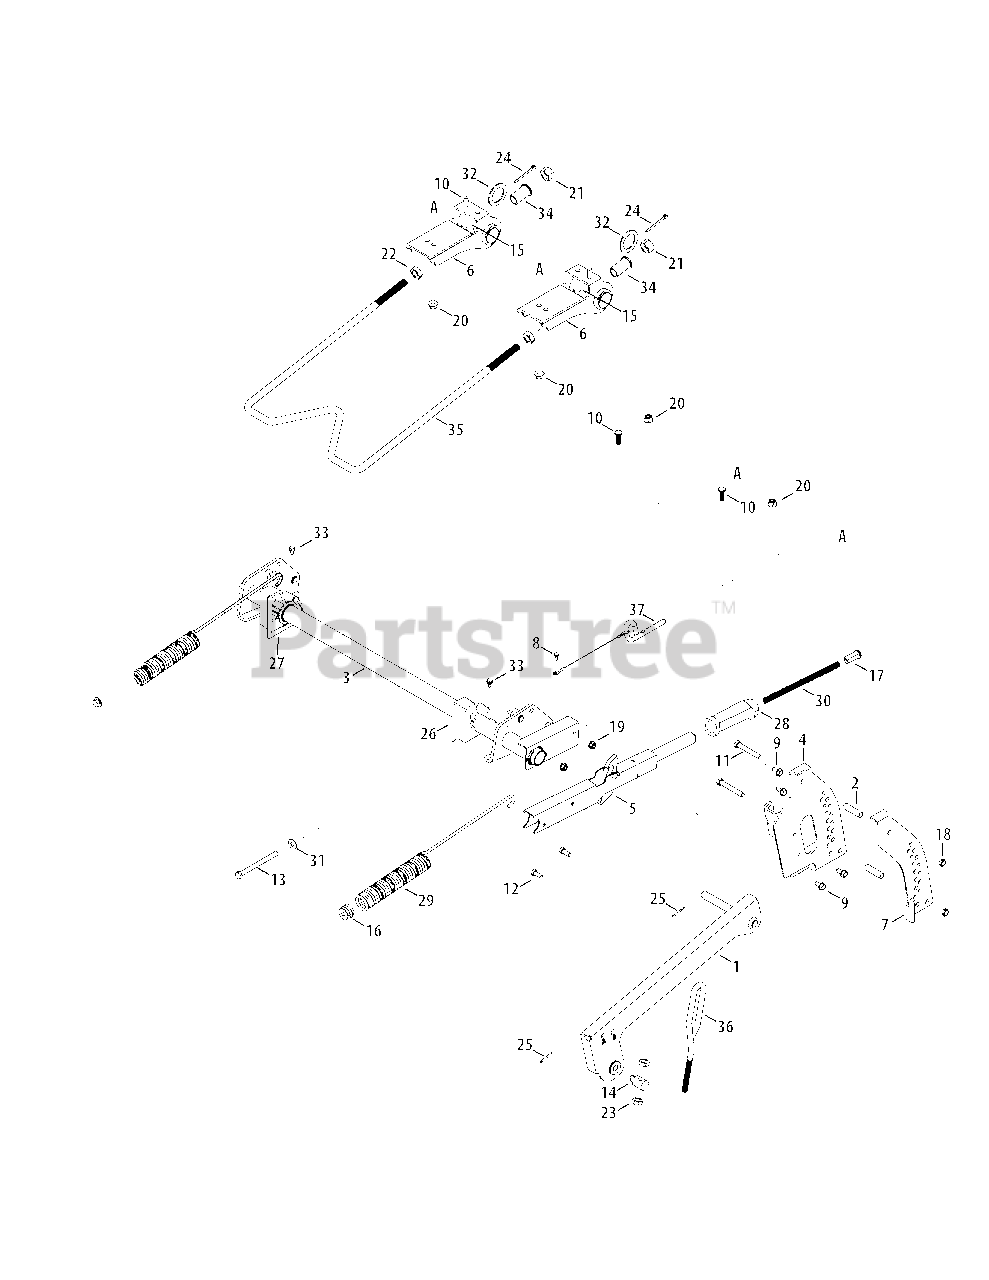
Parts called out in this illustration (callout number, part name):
1	Lift Arm, RH
1	Lift Arm, LH
2	Spacer, .386 x .63 x 1.75
3	Deck Lift Shift Assembly
4	Index Bracket Assembly
5	Latch Handle Assembly
6	Deck Hanger Bracket
7	Outer Index Bracket
8	Screw, #10-16, .50
9	Hex Washer Screw, 5/16-18 x .750
10	Hex Screw, 3/8-16 x 1.00
11	Hex Head Screw, 3/8-16 x 2.50
12	Hex Cap Screw, 5/16-18 x .75
13	Hex Screw, 3/8-16 x 4.25
14	Ferrule, .496 x .528
15	Pivot Pin, 1.25
16	Spring Insert
17	Handle Button
18	Jam Lock Nut, 3/8-16
19	Flange Lock Nut, 5/16-18
20	Flange Lock Nut, 3/8-16
21	Nylock Nut, 5/8-11
22	Jam Nut, 5/8-11
23	Nut,Hex Nylok 1/2-13
24	Cotter Pin, 3/16 x 2.0
25	Cotter Pin 1/8 x 1.25
26	Deck Lift Bracket
27	Deck Lift Bracket, LH
28	Grip, Deck Lift Handle
29	Extension Spring, 1.485 OD x 17.58
30	Spring, Compression, .4 x 8.52
31	Flat Washer, .385 x .870 x .092
32	Flat Washer, 1.875 x 1.38 x .097
33	Shoulder Screw, .500 x 1/4-20
34	Flange Bearing, .875 x .702 x 1.10
35	Deck hanger Rod, 5/8
36	Lift Adjust Link
37	Lock Rod, .375
